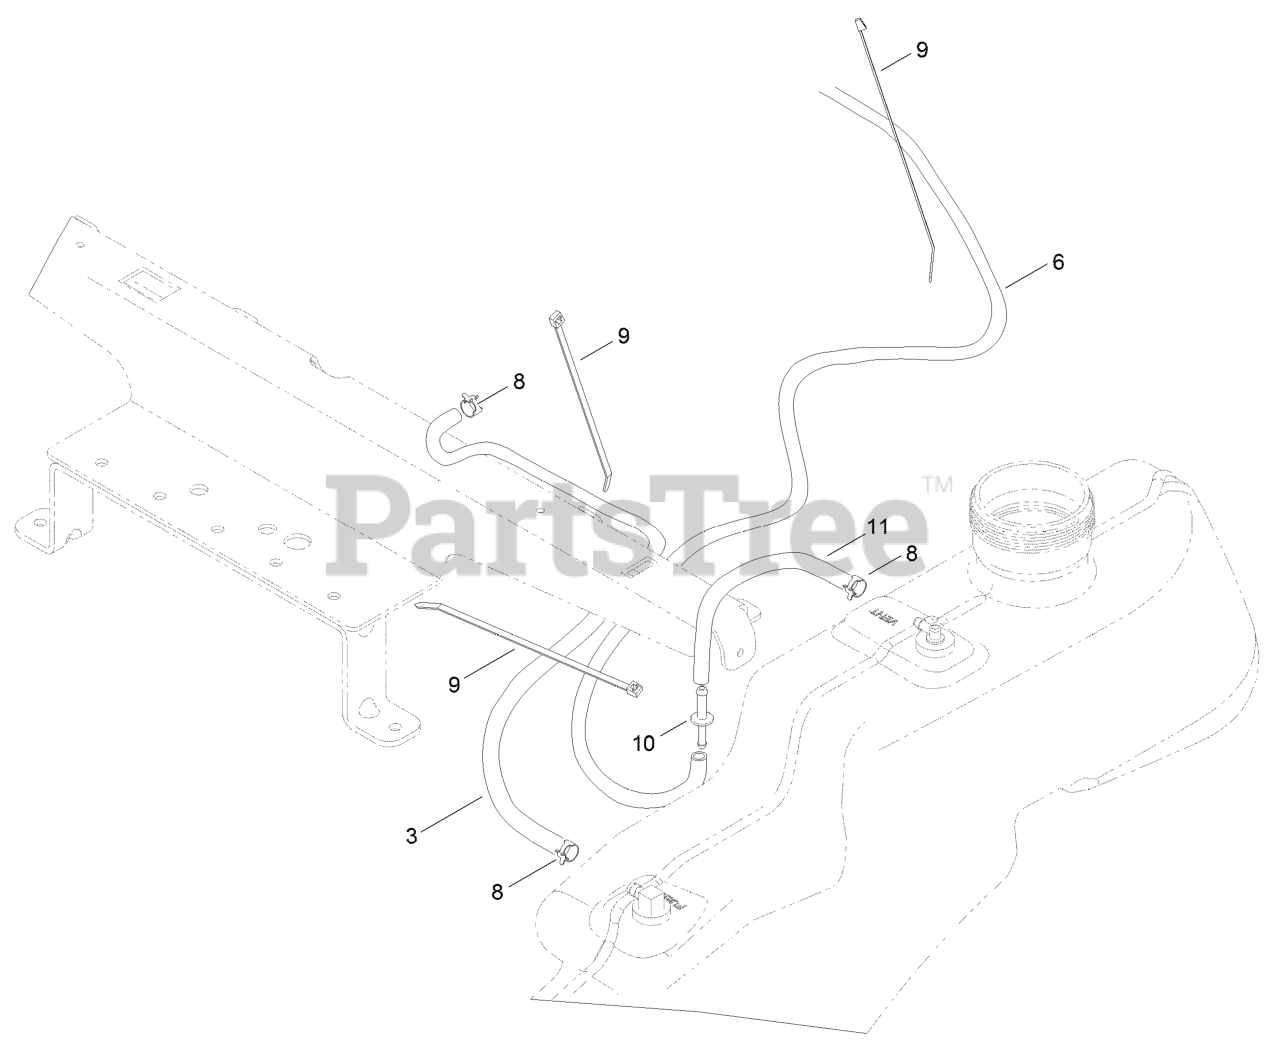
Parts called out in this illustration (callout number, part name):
3	HOSE-FUEL
6	HOSE-FUEL
8	CLAMP-HOSE
9	TIE-CABLE
10	ADAPTOR-ORIFICE
11	HOSE-FUEL
